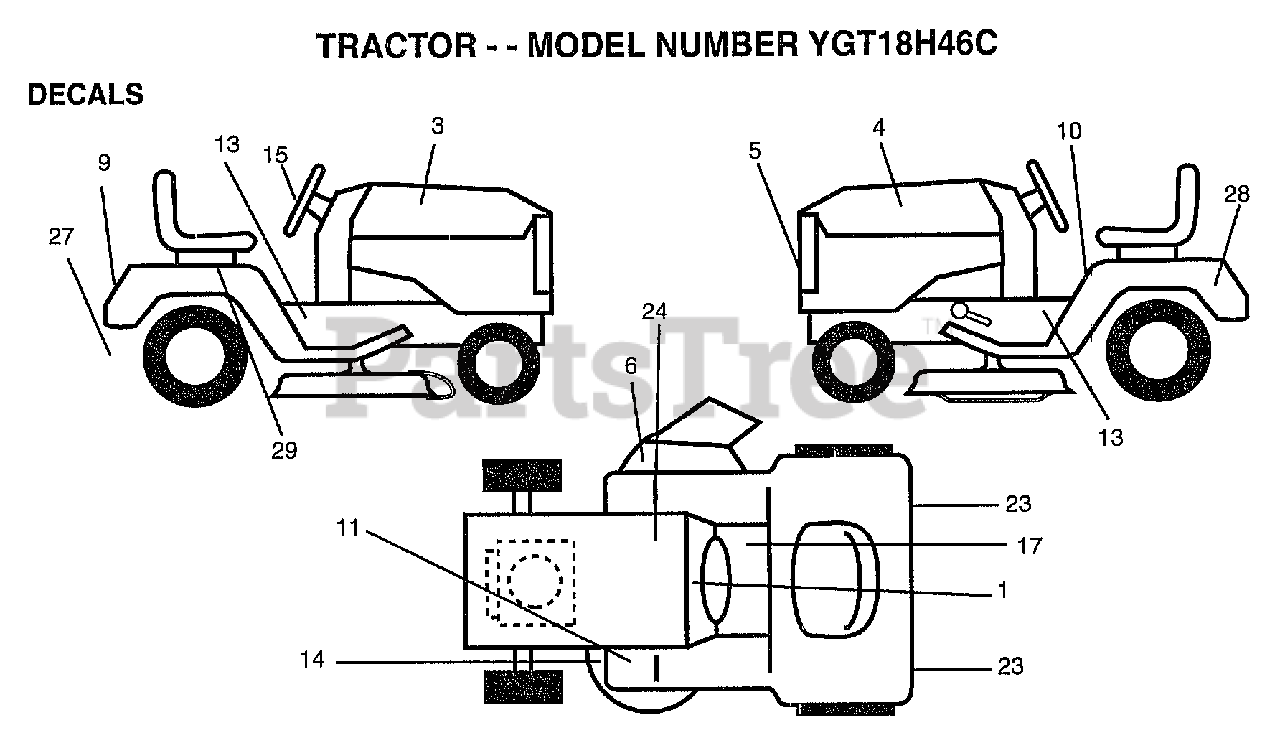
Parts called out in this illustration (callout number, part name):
1	DECAL OPER INSTR.
3	"DECAL HOOD,RH,18H"
4	"DECAL-HOOD,LH,18H"
5	DECAL GRILLE
6	"DECAL, WARNING"
9	DECAL FENDER
10	DECAL.CAUT.ENG/FR
11	DECAL T
13	"DECAL-CHASSIS,46"""
15	DECAL INS STRG WH
17	DECAL BRAK PARK
23	REFLECTOR-TAIL YT
24	DECAL.BATRY.3-3908
27	DECAL D-BAR CNTRL
28	DECAL FENDER LH
29	DECAL FENDER RH
